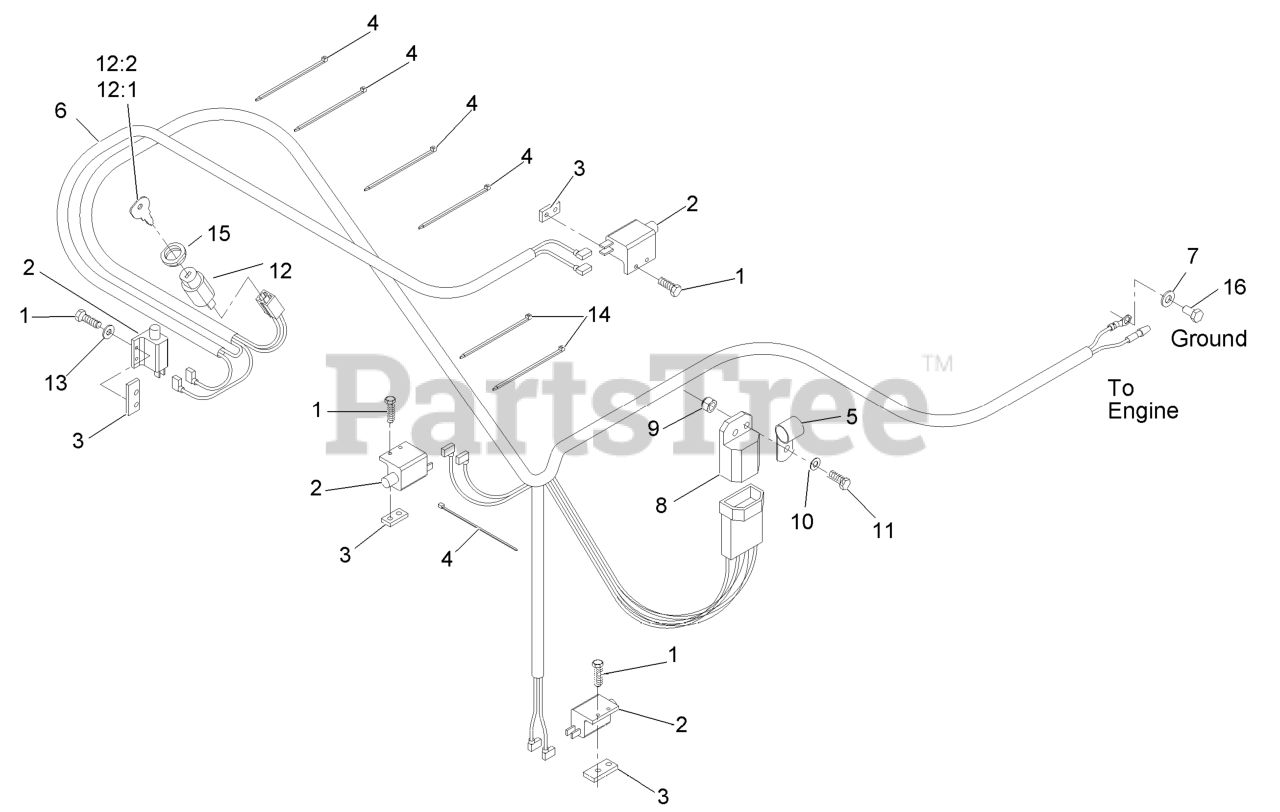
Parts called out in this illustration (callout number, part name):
1	SCREW-PPH
2	SWITCH-OPEN, NORMALLY
3	PLATE-TAPPED
4	TIE-CABLE
5	CLIP-LOOM
6	HARNESS,WIRING KA PULL ST
7	WASHER-PLAIN
8	MODULE-INTERLOCK
9	NUT-LOCK, NI
10	WASHER-FLAT
11	SCREW-HH
12	SWITCH & KEY (INCLUDES NU
12:1	KEYS-IGNITION (SPARE PAIR
12:2	KEY-IGNITION
13	WASHER-FLAT
14	TIE-PLASTIC
15	NUT-SWITCH, IGNITION
16	SCREW-HH
